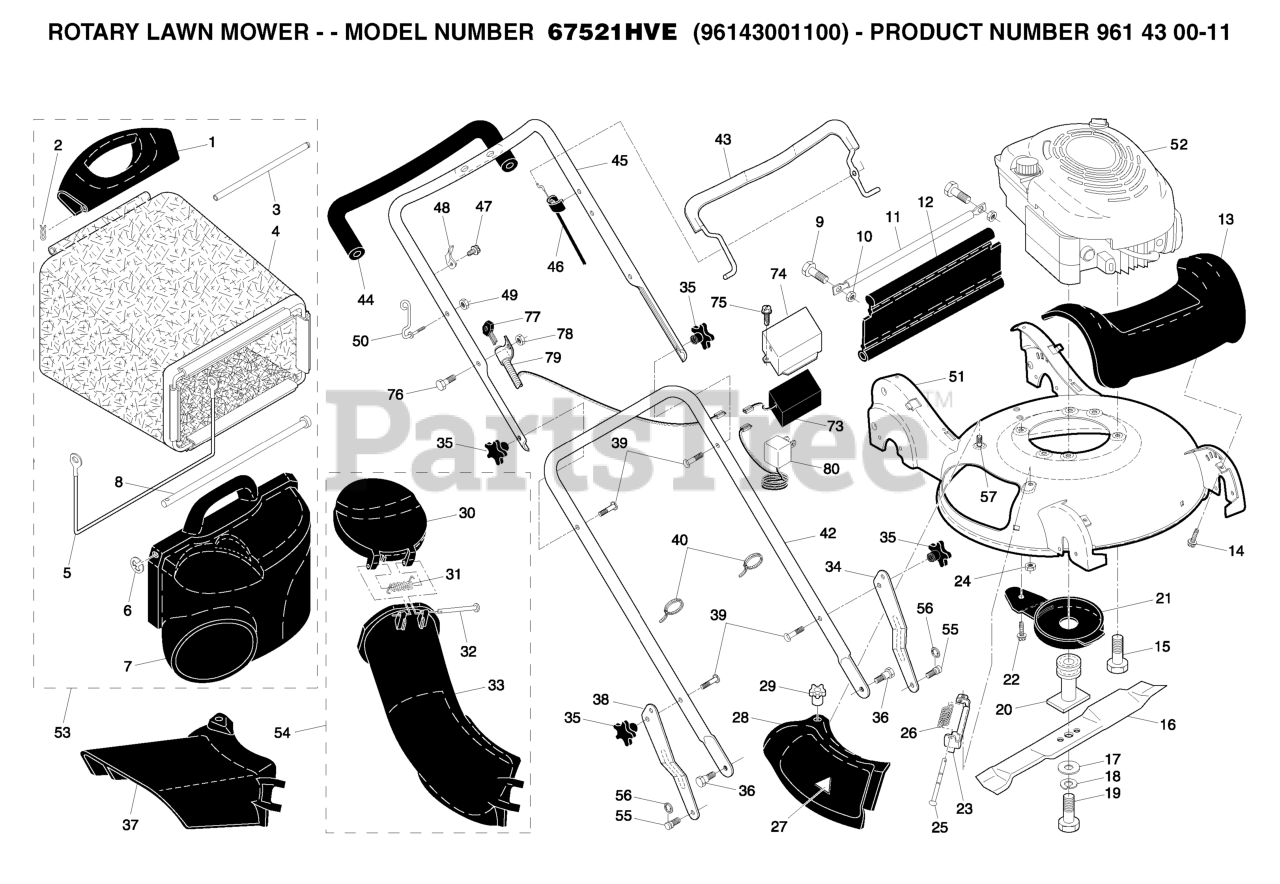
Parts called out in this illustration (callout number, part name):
1	HANDLE.GRASSBAG.REAR.H-GRAY
2	COTTER PIN (3 2)(2 2MC)
3	ROD.REAR.HANDLE.YELLOW
4	GBAG.5323247.SILVER.HUSQ
5	FRAME, GRASSBAG
7	DOOR, GRASSBAG
8	ROD, PIVOT
10	LOCKNUT.NYLOC.1/4-20
11	TUBE, REAR SKIRT
12	SKIRT.REAR.21 " HI-VAC
13	COVER, FRONT
14	SCREW
15	BOLT 3/8-16X1-1/8
16	BLADE.21.PUSH/RWGD/FWG
17	WASHER,HARDEN
18	LOCKWASHER
19	BOLT.HD.HEAD.3/8-24X2.50 (2 2)
20	ADAPTER.BLADE
21	DEBRIS SHEILD
22	SCREW 1/4X20
23	BRACKET.ASM.HINGE
24	LOCK NUT
25	ROD.HINGE.1/4"3.82"
26	SPRING.MULCH.DOOR
27	DECAL HYT
28	MULCHER DOOR
29	KNOB.MULCH.DOOR
30	CHUTE.DOOR.21.HV.H-GRAY
32	ROD.HINGE.1/4"3.82"
33	DISCHARGE CHUTE PLASTIC
34	ADJUSTMENT BRACKET, LOWER LH
35	KNOB.HANDLE.STAR.HUSQ.GRAY
36	SHOULDER BOLT
37	GUARD.CLIP.ON.21.HV.GRAY
38	BRACKET.ADJ.LOWER.HDL.RT.GREY
39	BOLT, HANDLE 5/16-18X1.75
40	TIE GUIDE
42	HANDLE.LOWER.GREY
43	BAIL CONTROL
44	GRIP.HANDLE.FOAM.WIDE.(1 SIDE)
45	HANDLE.ASM.UPPER.W/GRIP
46	RB ENGINE ZONE CONTROL CABLE
48	BRACKET
49	NUT
50	GUIDE.ROPE.WALK.MOWER
53	RP_GBAG.ASM.21 HV"CROWN"
54	CHUTE.LOWER.ASM.WALK.MOWER
55	STUD, SHOULDER
56	E-RING 7/16 RE
57	STUD.INSERT
73	BATTERY.AMP.CONNECTOR
74	COVER BATTERY
75	SCREW.HX.13X.750
77	KEY.MOLDED
78	LOCK NUT
79	CONTROL.START.KEY.HV
80	RP CHARGER.BATTERY
